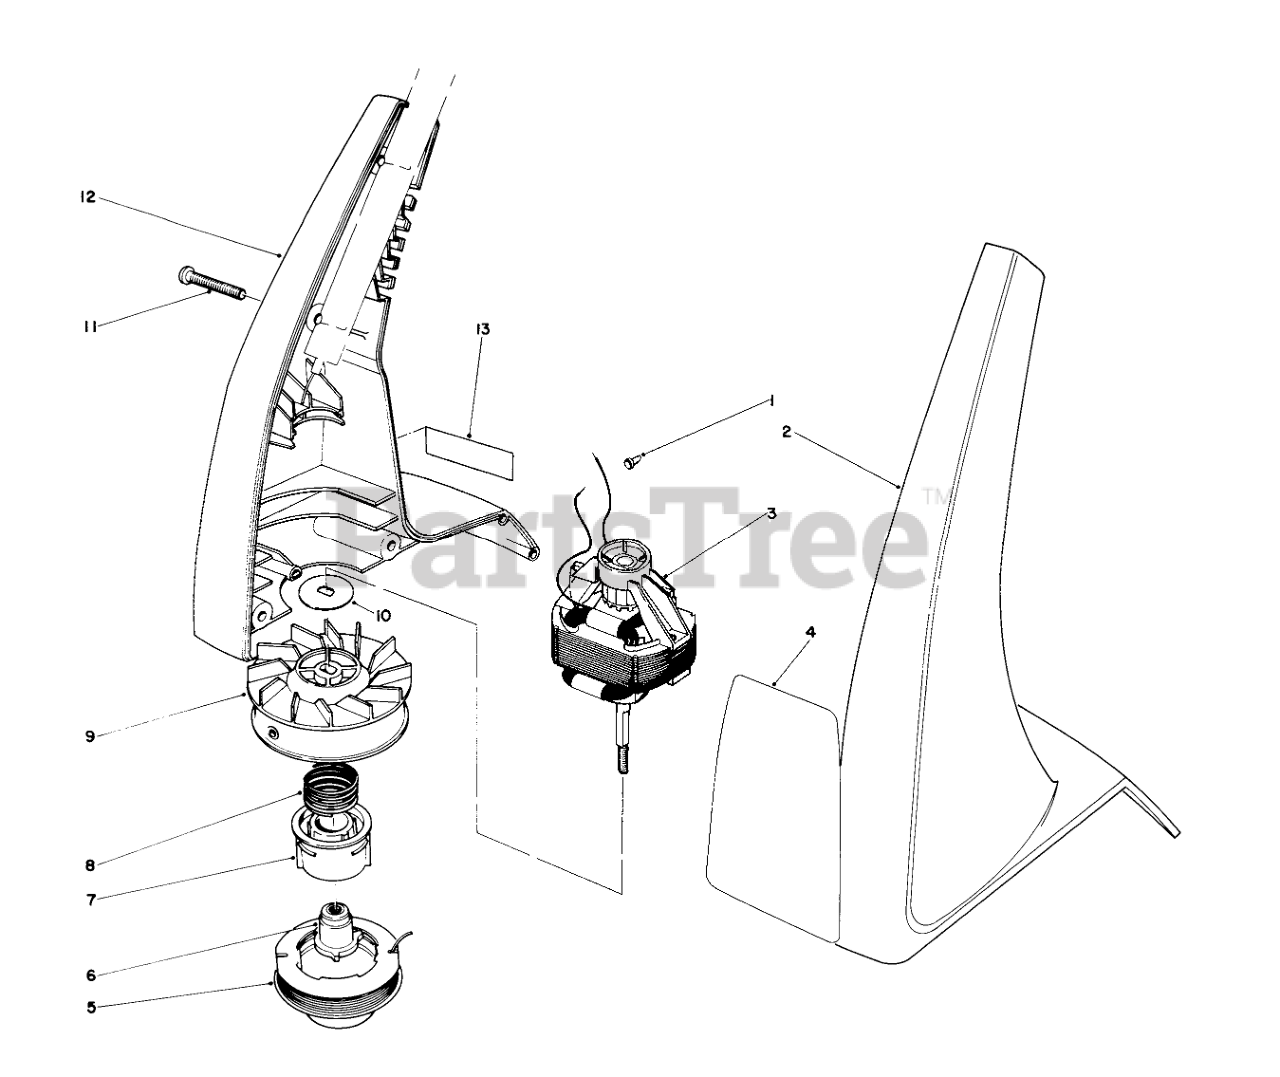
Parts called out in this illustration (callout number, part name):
1	CONNECTOR WIRE JOINT
2	L.H. HOUSING, 910
3	MOTOR, 910 TRIMMER
4	910 DECAL
5	Cutting Line (12- .05 Dia.)
6	DRIVER
7	CORE - SPOOL
8	Spring
9	Drum w/Eyelet
10	MOTOR WASHER
11	Screw
12	Housing-R.H.
13	Decal
